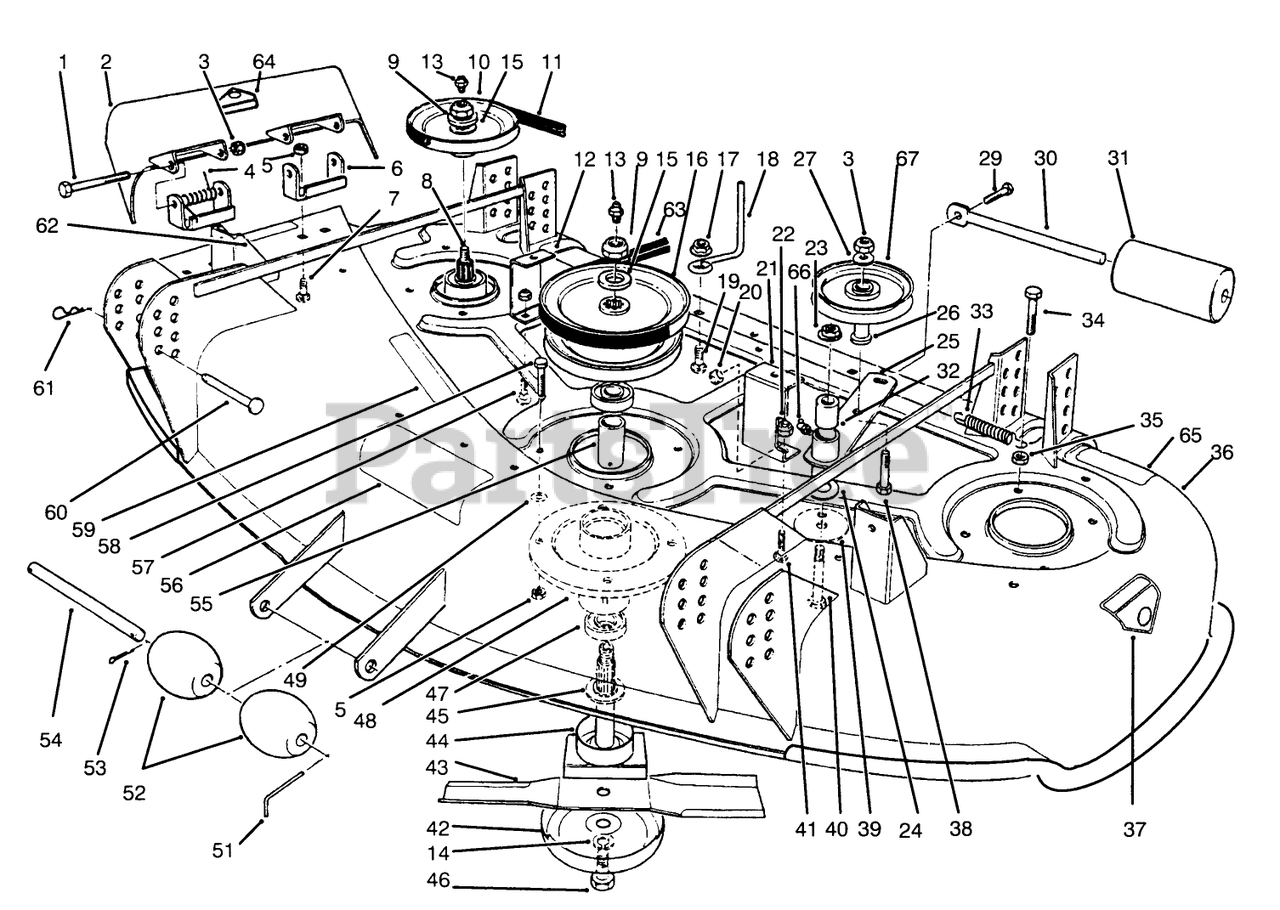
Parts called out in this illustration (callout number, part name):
1	SCREW-HH
2	Deflector-Grass (Incl. Ref. #64)
3	NUT-HEX
4	SPRING
5	NUT-LOCK, CONE
6	PIVOT BRKT WA R/B
7	SCREW-CARR
8	SHAFT-SPINDLE
9	NUT-HEX
10	PULLEY-DECK
11	V-BELT
12	Bracket-Cover RH
13	FITTING-GREASE
14	WASHER-LOCK
15	WASHER
16	PULLEY-CENTER
17	NUT-HF
18	ROD-BELT
19	BOLT-CARR
20	NUT-LOCK, NI
21	Bracket-Cover
22	NUT-LOCK, NI
23	NUT-HF
24	WASHER
25	IDLER ARM ASM
26	BUSHING-PULLEY
27	WASHER-FLAT
29	SCREW-HH
30	ROD-ROLLER
31	ROLLER-DECK
32	SPACER
33	Spring-Extension
34	SCREW-HH
35	NUT-JAM
36	Deck Asm. (Incl. Ref. #37, 56, 62, 64, & 65)
37	DECAL-DANGER
38	SCREW-HH
39	WASHER-END
40	SCREW-HH
41	SCREW-CARR
42	Anti-Scalp Cup
43	Blade
44	SHAFT-SPINDLE
45	SPACER-SPINDLE
46	SCREW-BLADE
47	BEARING-BALL
48	HOUSING-SPINDLE
49	WASHER-FLAT
51	PIN-SPECIAL
52	ROLLER
53	PIN-COTTER
54	SHAFT-ROLLER
55	SPACER-BEARING
56	DECAL-DANGER, THROWN OBJECT
57	BOLT-CARR
58	SCREW-HH
59	DECAL-DANGER
60	PIN-CLEVIS
61	PIN-HAIR
62	DECAL-DANGER
63	V-BELT, DRIVE
64	DECAL-DANGER
65	DECAL-TORQUE
66	Fitting-Grease
67	Pulley-Idler
